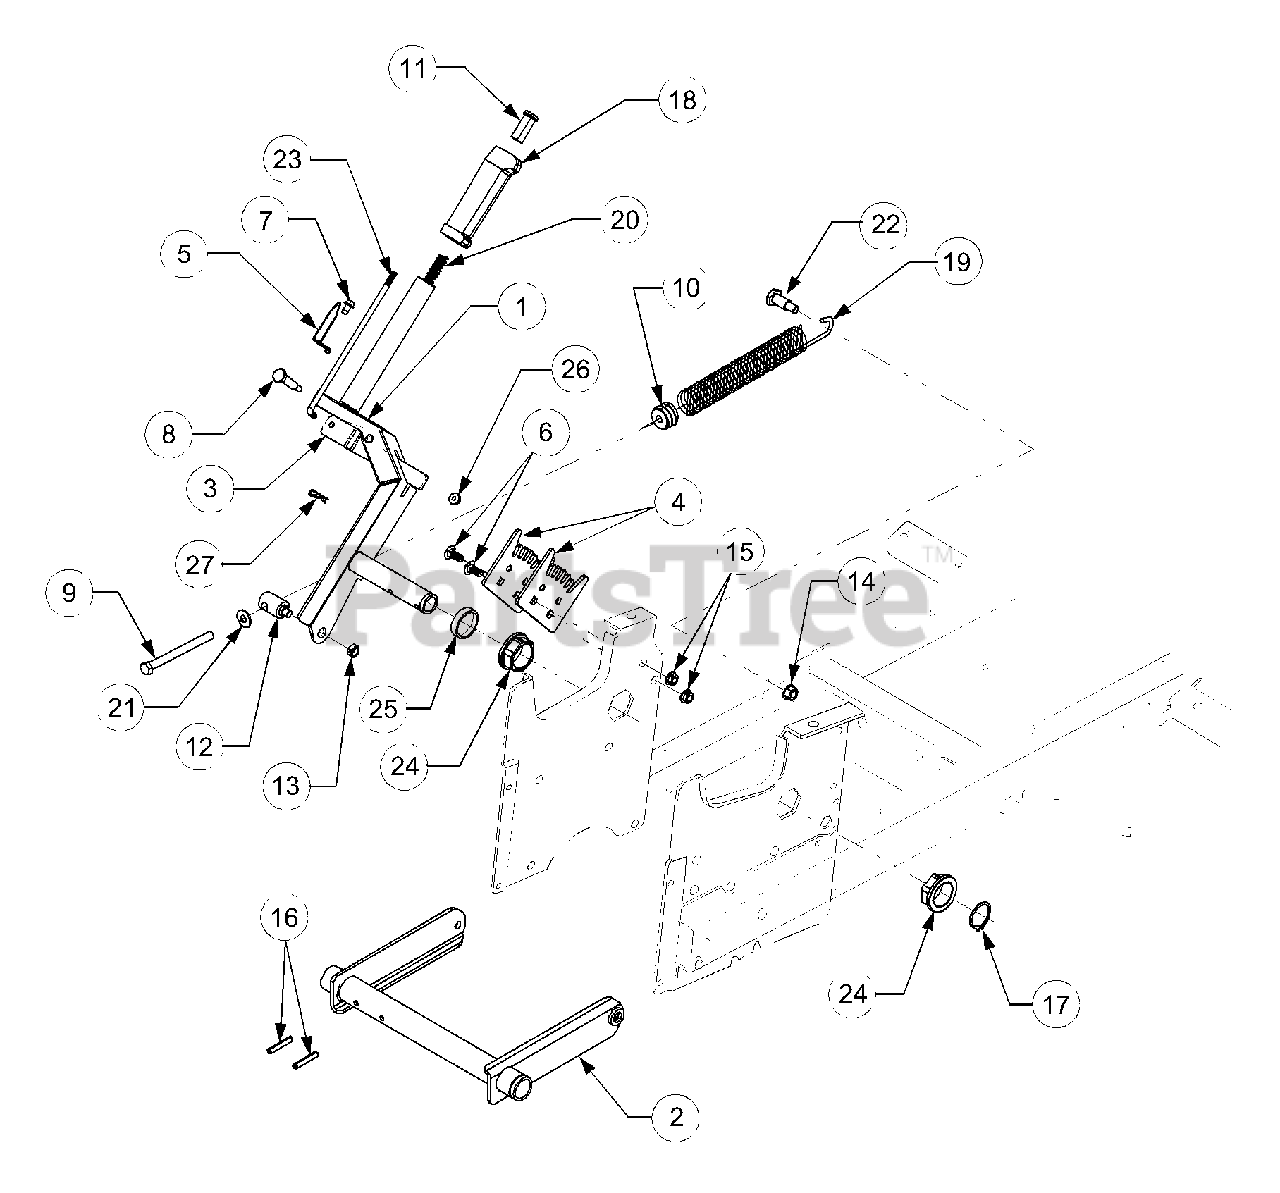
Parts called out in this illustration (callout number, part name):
1	Handle Assembly, Lift
2	Shaft Assembly, Lift
4	Bracket, Lift Index
5	Indicator, Lift Height
6	Bolt, Carriage, 5/16-18 x .75
7	Screw, Hex Wash Tapp, 1/4 x .5
8	Screw, Shoulder, .374 x 1.375
9	Screw, Hex Cap, 3/8-16 x 4.25 GR5
10	Insert, Spring
11	Button, Handle
12	Ferrule, Adjustment
13	Nut, Hex Center Lock, Jam, 3/8-24
14	Nut, Hex Flanged Lock, 3/8-16
15	Nut, Hex Flanged Top Lock, 5/16-18
16	Pin, Spiral Spring, 1/4 Dia x 1.5
17	Ring, Snap, 1.25 Dia Shaft
18	Grip, Lift Handle
19	Spring, Extension
20	Spring, Compression
21	Washer, Flat, .385 x .87 x .06
22	Bolt, Shoulder
23	Rod, Index
24	Bearing, Hex Flange, 1.25 ID
25	Spacer, 1.28 ID x 1.5 OD x .335 Lg
26	Nut, Hex Flange Lock, 1/4-20
27	Pin, Internal Cotter
